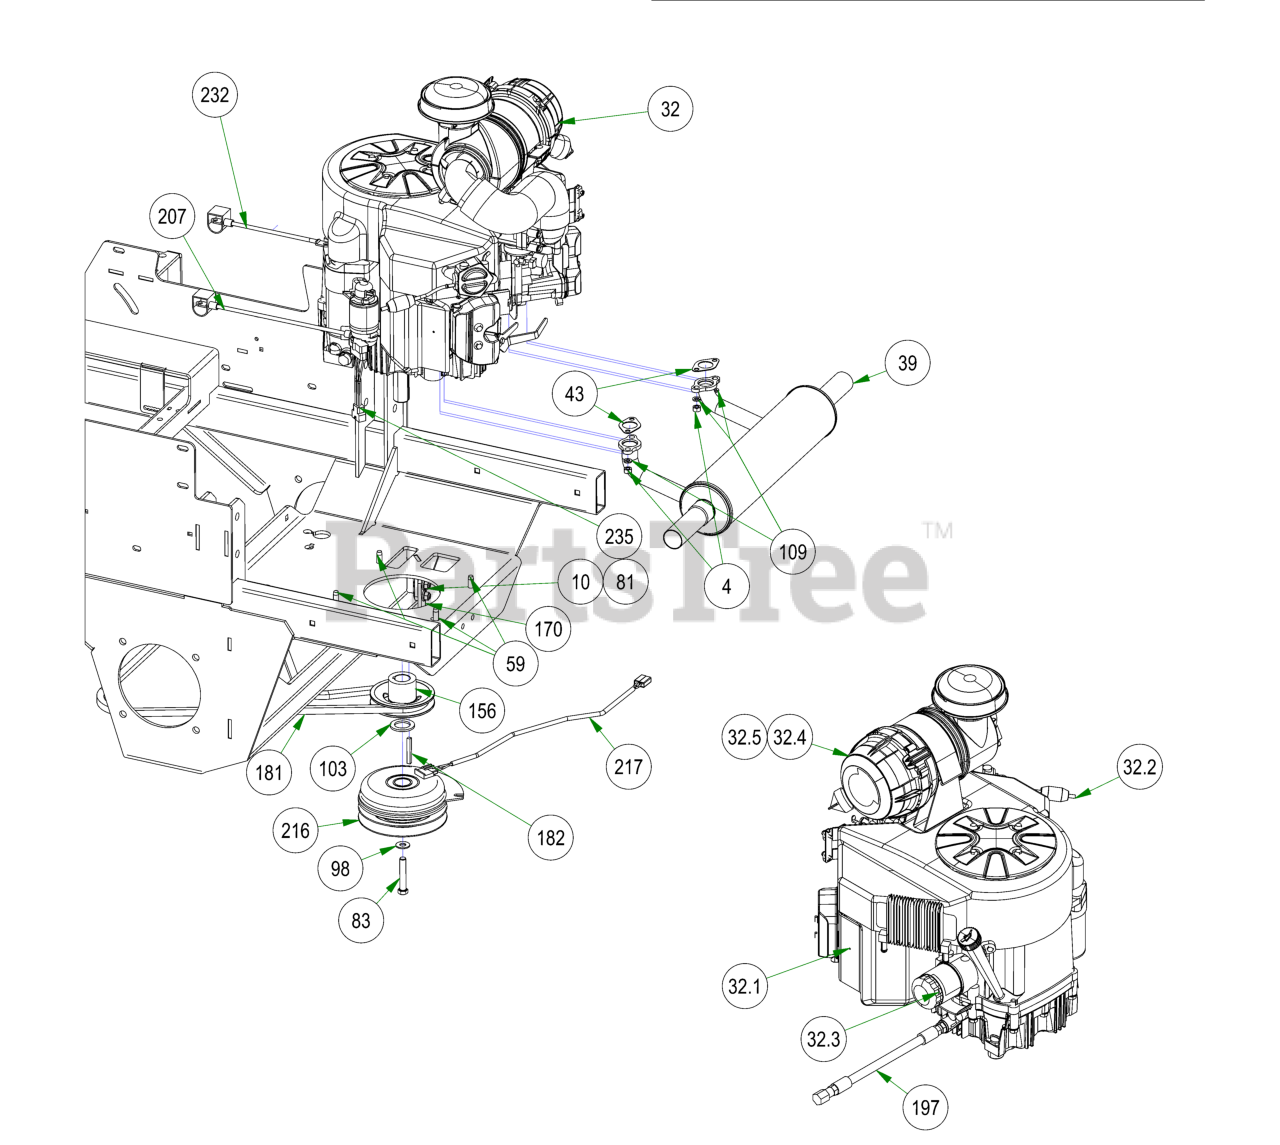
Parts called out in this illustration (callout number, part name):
4	M8-1.25 DIN 934 HEX NUT (CL.8) ZINC
10	3/8-16 NYLON INSERT FLANGE LOCKNUT (GR.F) ZINC
32	Kawasaki FX850 Engine
32.1	Spark Plug - Kawasaki
32.2	Universal Inline Fuel Filter
32.3	Oil Filter
32.4	Canister Air Filter- Outer
32.5	Canister Air Filter- Inner
39	2019 Rebel/Rogue Kawasaki 850 Muffler
43	Exhaust Gasket
59	3/8-16 X 1-1/8HEX WASHER UNSLOT SERRATED
81	3/8-16 X 1 CARRIAGE BOLT (GR.5) ZINC
83	7/16-20 X 2-1/2 HEX Bolt GR 8 W/ Patch
98	3/8 FLAT WASHER USS (1" OD) ZINC
103	1.140 ID X 1.750 OD X .132 THICK FLAT WASHER PLAIN
109	5/16 SPLIT LOCKWASHER ZINC
156	4 3/4 Motor Pulley
170	Rebel Clutch Tab
181	2019 Rebel Pump Belt
182	1/4 X 2 SQ MACHINERY KEY 1018 STL PLAIN
197	Kawasaki Oil Drain
207	14" Red Battery Cable-Base Outlaw
216	Clutch Assembly
217	Clutch Pigtail
218	2022 Rebel Frame
232	Starter Cable
235	2019 Harness Adaptor-Gen2 FX-ALL
